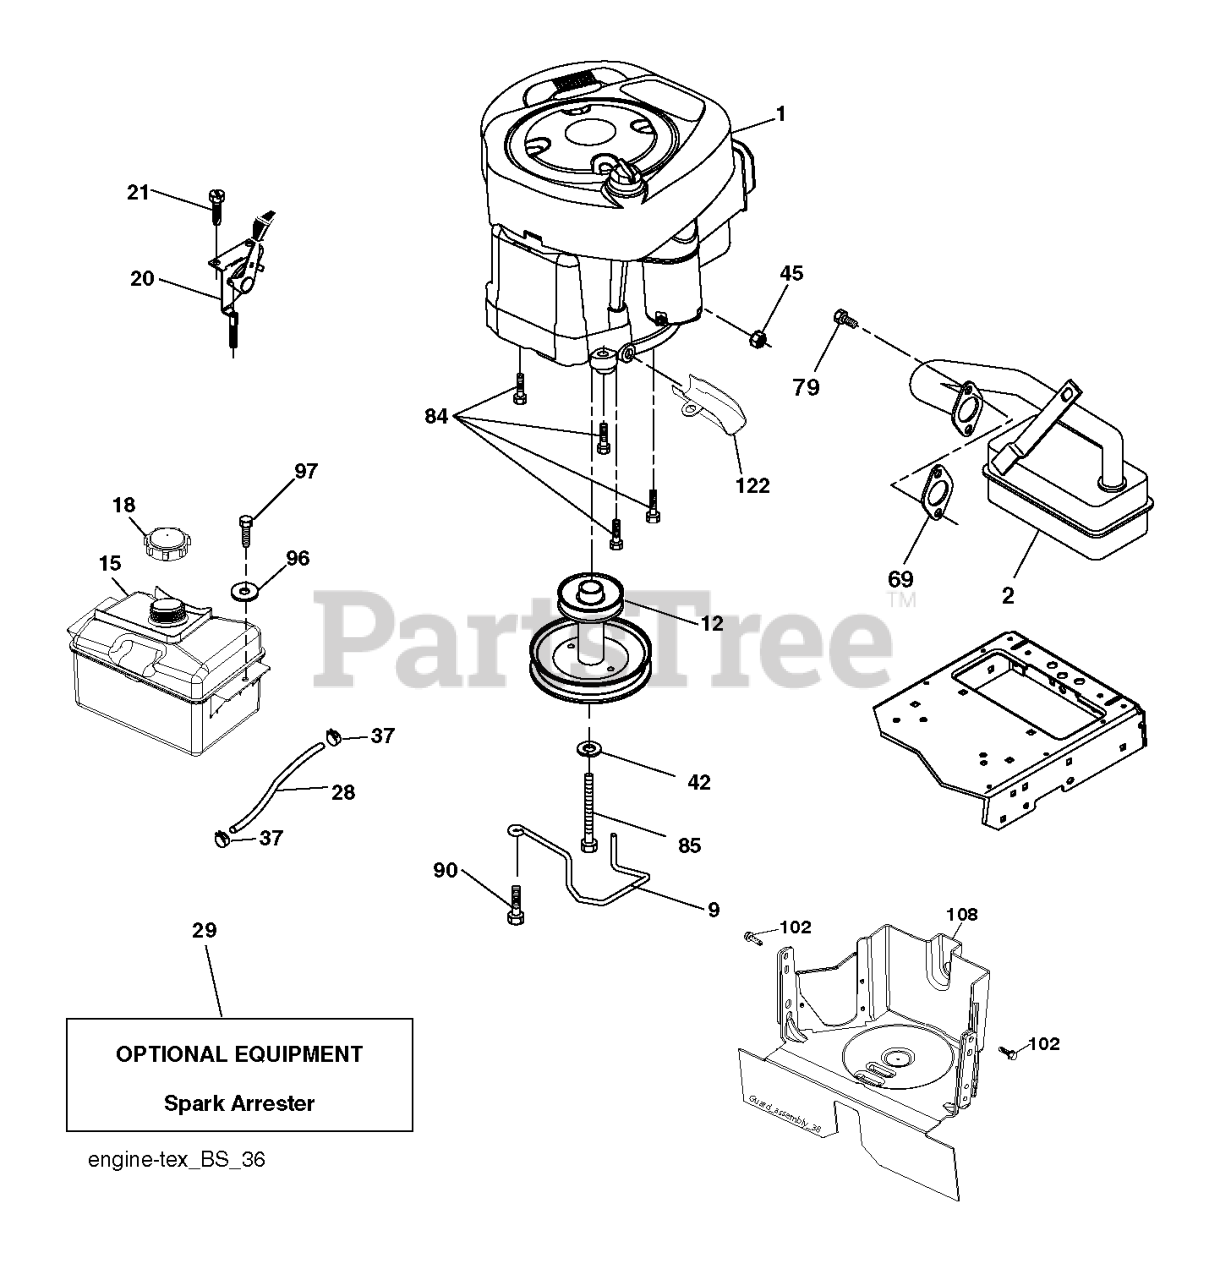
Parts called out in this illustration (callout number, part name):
2	MUFFLER.B&S.MODEL.21.11HP.OHV
9	KEEPER.BELT.ENGINE.3.25 (3 2)
12	PULLEY.ENG.CL.MECH.SLVR.LT/YT
15	RP TANK FUEL FRT 1.5 GAL
18	CAP ASM.FUEL.2.25"FR.
20	CONTROL.TH/CK.C.
21	SCREW.#10 X 0.750.BOS
28	LINE.FUEL.20
29	KIT.SPARK ARRESTOR 794945 B&S
37	HOSE CLAMP
42	LOCKWASHER
45	NUT
69	REPL BY 532 27 22-93
79	SCREW.SOCKET HD.5/16-1
84	SCREW.3/8-16
85	BOLT HEX 7/16-20X4-1/4"
90	SCREW 3/8-16X1
96	WASHER
97	SCREW HEXWSHR 1/4-20X3/4
102	SCREW
108	COVER PULLEY
122	EXTENSION DRAIN OIL
